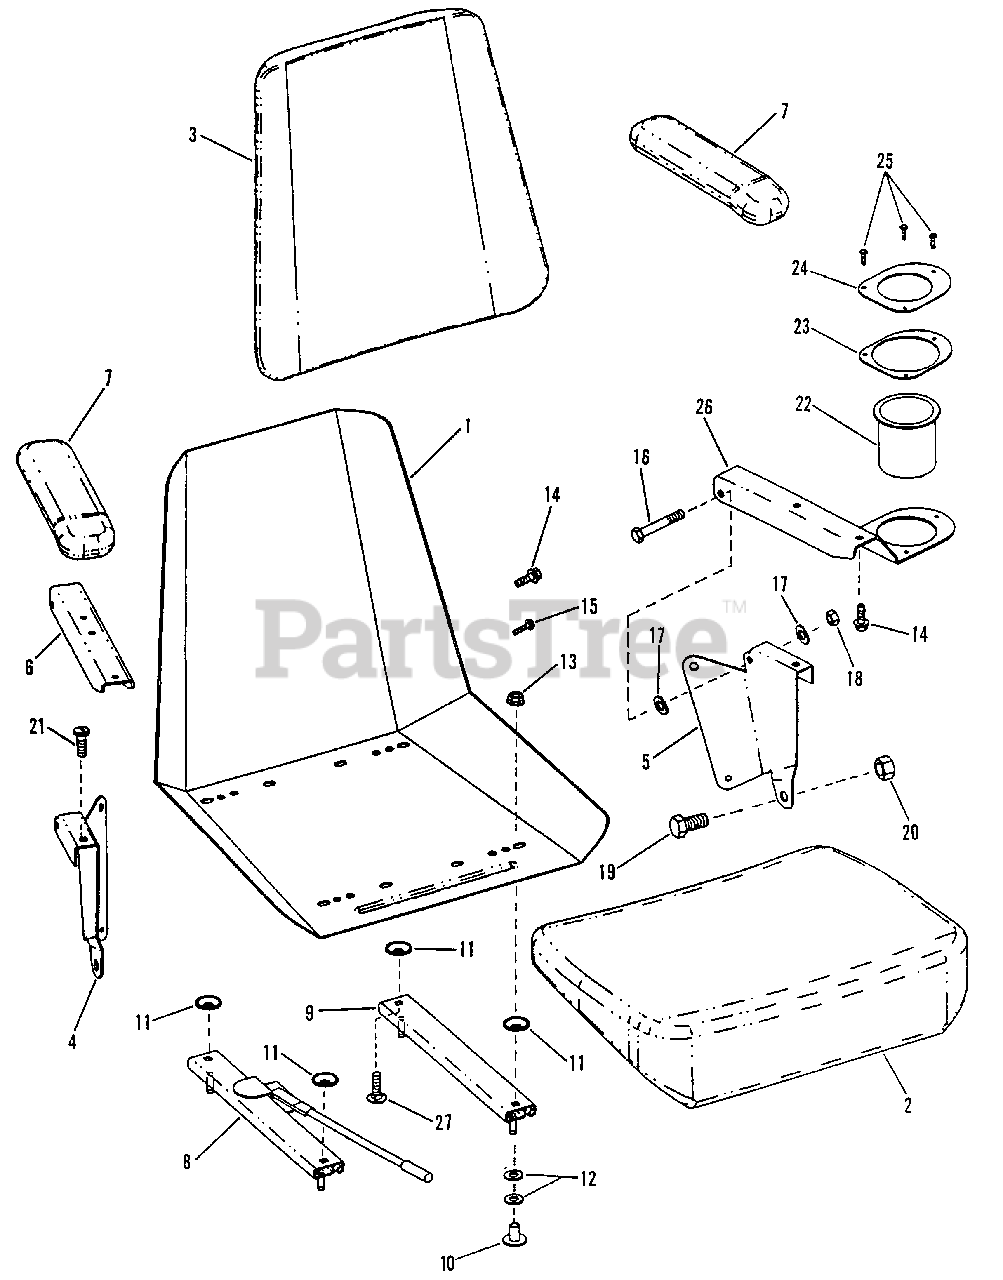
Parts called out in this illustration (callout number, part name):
1	PAN, Complete
2	CUSHION, Seat
3	CUSHION, Back
4	BRACKET, Armrest R.H.
5	BRACKET, Armrest L.H.
6	CHANNEL, Armrest
7	ARM PAD, Grey
8	ADJUSTER (with lock)
9	ADJUSTER (without lock)
10	STUD GUARD
11	SPACER, Bell
12	WASHER, 5/16" Flat
13	NUT, 5/16-18 Hex Flange Lock, Grade 5
14	SCREW, 1/4-20 x 3/4" Phillips
15	SCREW, #8 x 1/2" Set
16	BOLT, 5/16-18 X 2", GD5
17	WASHER, .406 I.D. Poly
18	NUT, 5/16-18 Hex Head Centerlock, Grade B
19	SCREW, 1/2-13 x 1" Hex Head Cap, Grade 5
20	NUT, 1/2-13 Hex Head Centerlock, Grade 5
21	SCREW, 5/16-18 x 1" Slotted Pan Head
22	HOLDER, Beverage
23	SPACER, Cupholder
24	COVER, Cupholder
25	RIVET, 3/16" pan Head
26	BRACKET, Armrest Cup Holder
27	BOLT, 5/16-18 x 1" Short Neck Carriage, Grade 5
